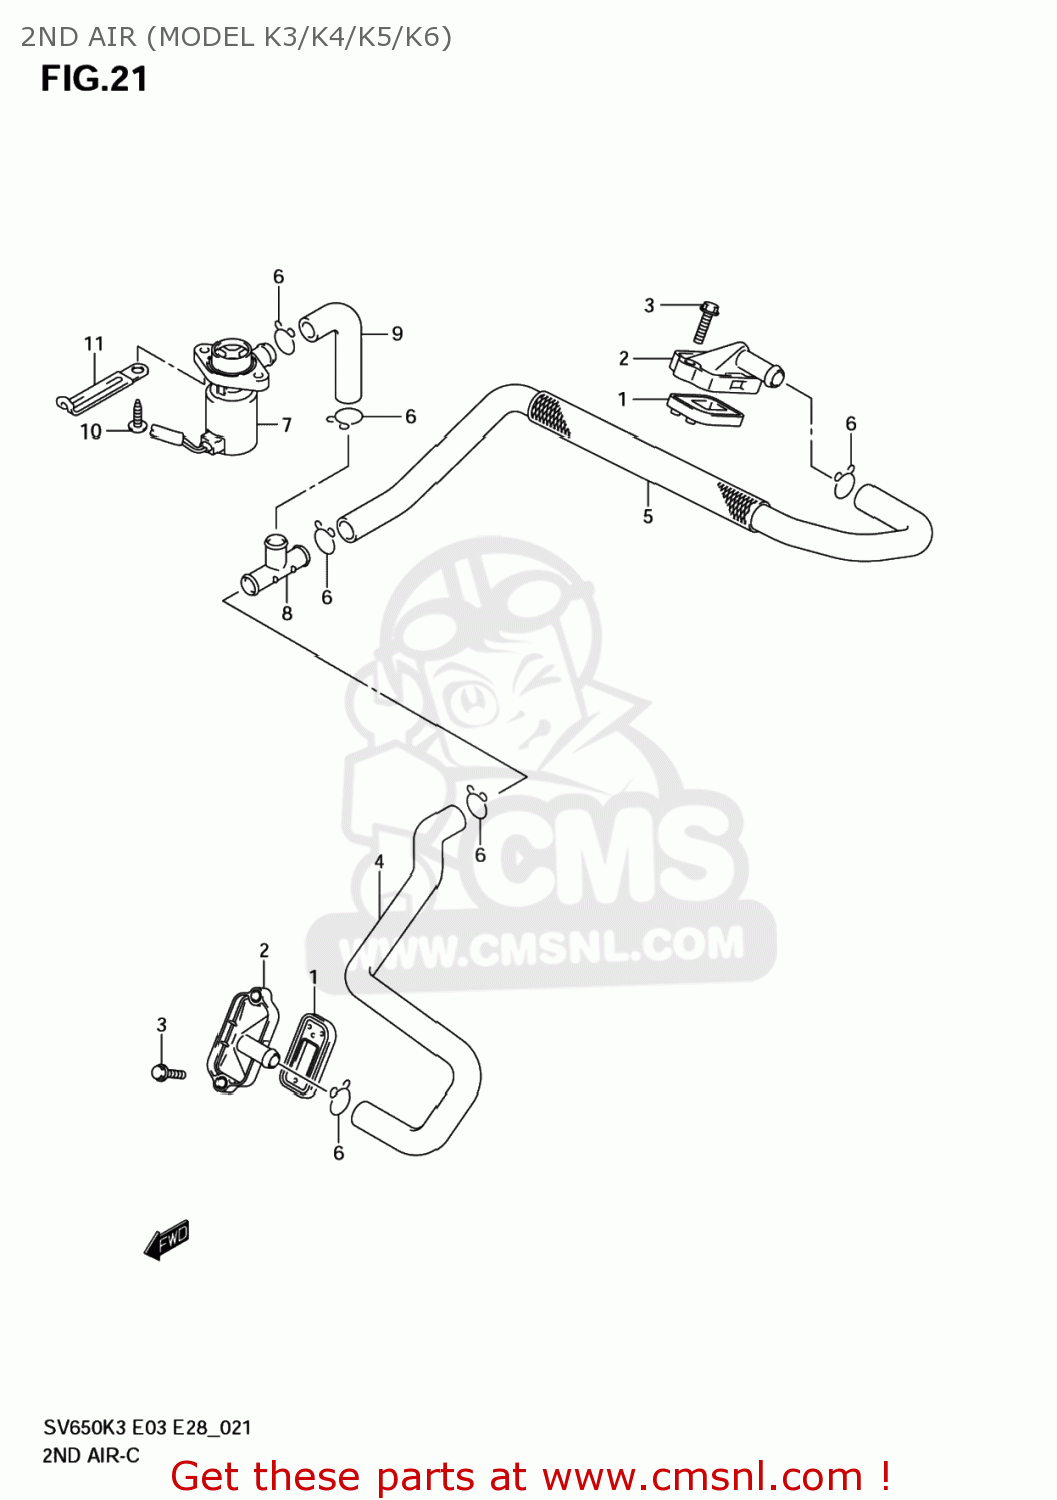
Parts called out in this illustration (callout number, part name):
1	VALVE ASSY,2ND AIR REED
2	COVER,2ND AIR
3	BOLT(6X20)
4	HOSE,2ND AIR VALVE FR
5	HOSE,2ND AIR VALVE RR
6	CLIP
7	VALVE ASSY,AIR
8	JOINT
9	HOSE,2ND AIR CLEANER
10	SCREW
11	CLAMP(L:45)
